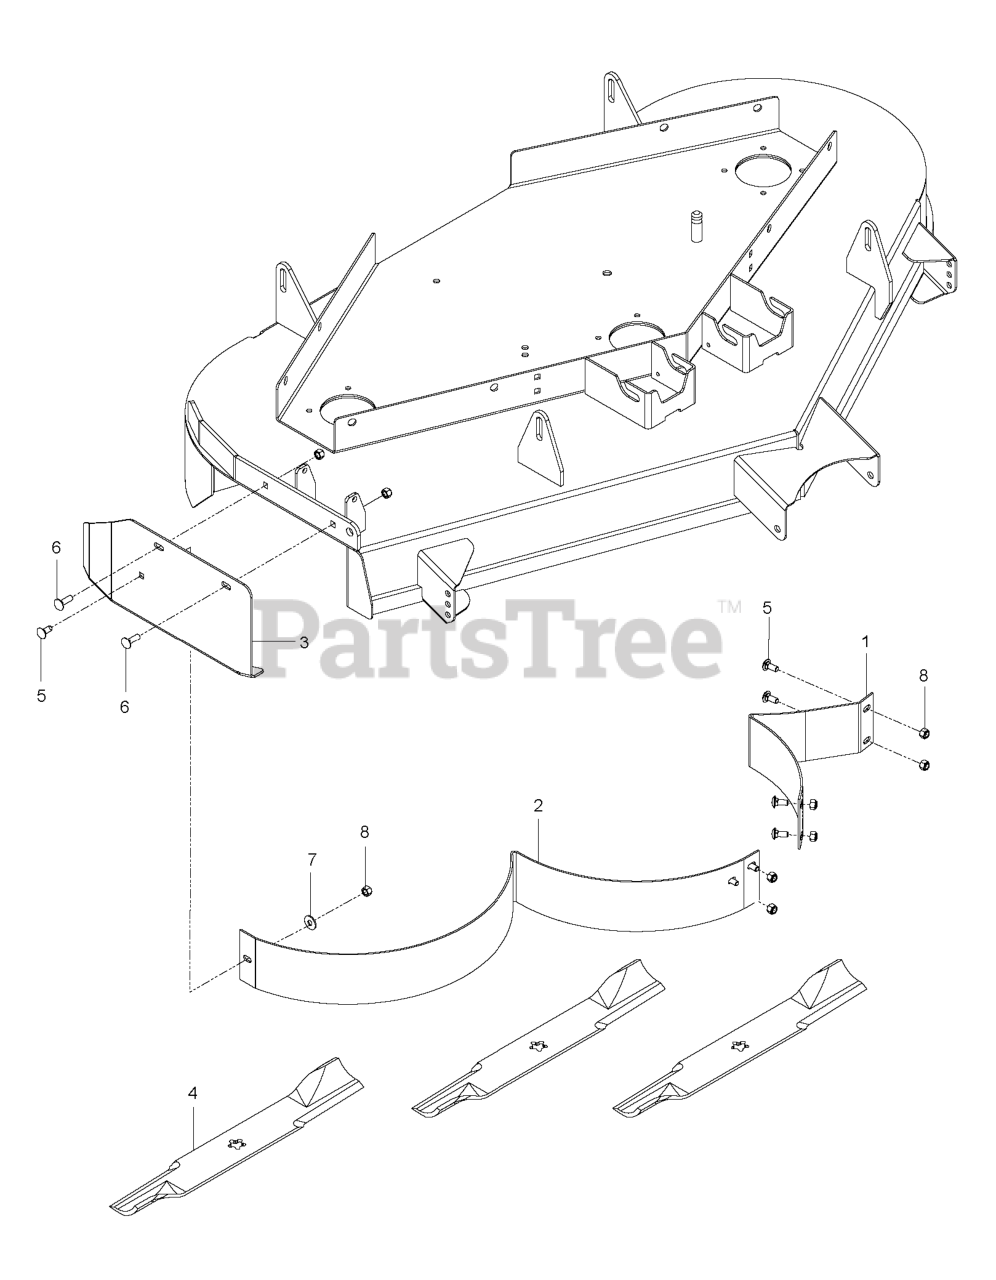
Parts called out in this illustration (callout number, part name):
1	48 MULCH BAFFLE - LH BLACK
2	BAFFLE.MULCH.48"RH BLACK
3	PLATE.MULCH.48".ZTR.BLACK
4	BLADE, 16-1/4" GATOR
5	RP BOLT 5/16-18 X3/4 ZN/YEL GR
7	WASHER 5/16 FLAT
8	NUT 5/16 NYLOC
